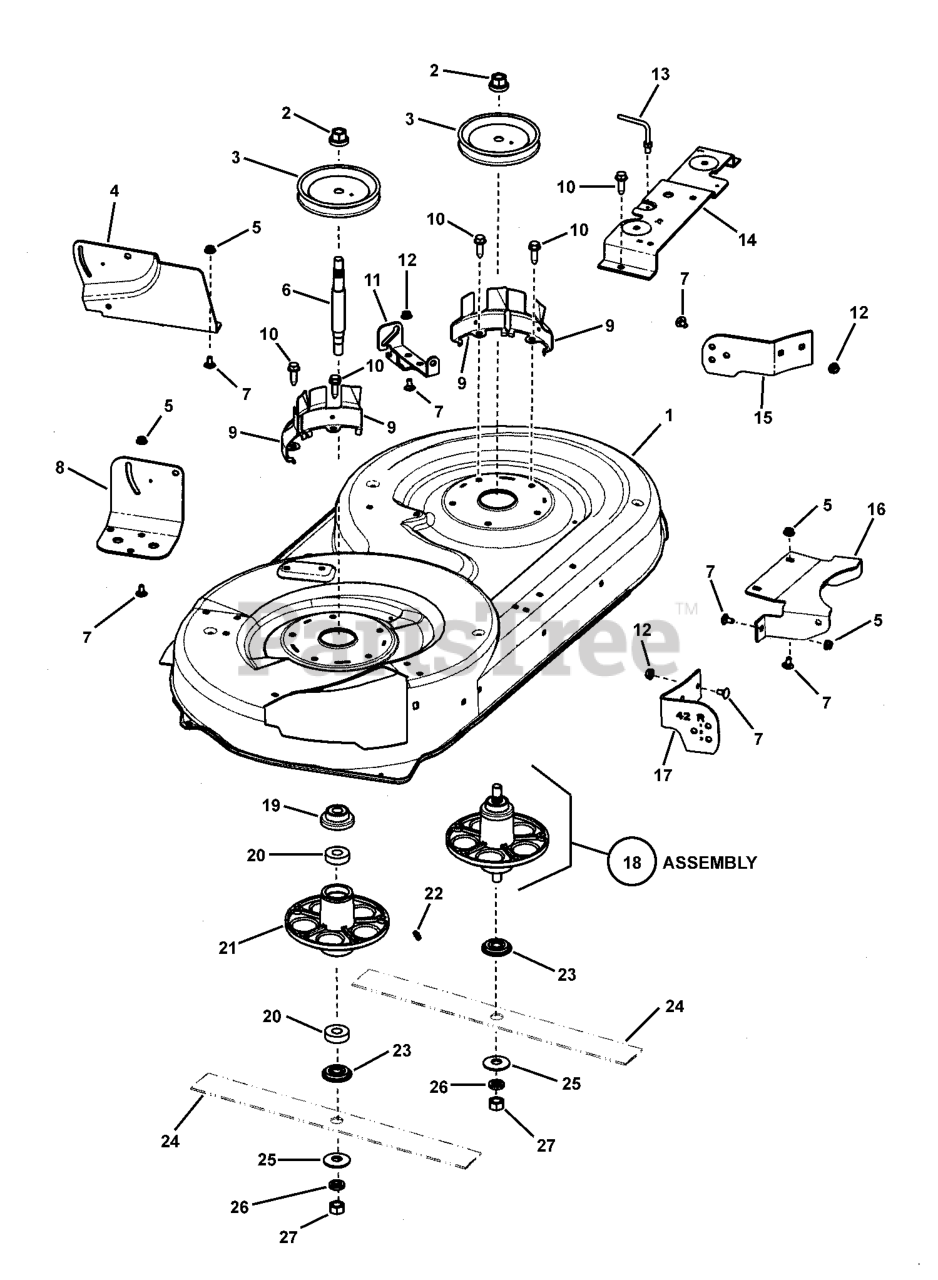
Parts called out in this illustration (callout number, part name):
1	HOUSING, 42" Mower Deck
2	NUT-NYLOCK RING - PULLEY 9/16-18
3	PULLEY, JACKSHAFT
4	BRACKET SUSPENSION, L.H. 42
5	HEX NUT, 5/16-18 FLANGE SER YZ
6	SHAFT, SPLINED
7	BOLT CARRIAGE, 5/16-18 X .62
8	BRACKET SUSPENSION, R.H. 42
9	SEGMENT - BELT GUIDE
10	HHST, 3/8-16X1.25
11	BRACKET - HINGE
12	NUT, HEX FLANGE LOCK, 5/16-18 NC
13	BELT GUIDE (5/16-18)
14	BRACKET - BRAKE MTG 42"
15	BRACKET LR GA WHEEL
16	BRACKET, FRONT HANGER
17	BRKT RH GAGE WHEEL 42"
18	JACKSHAFT HOUSING ASSY
19	SPACER, PULLEY
20	BALL BEARING, JACKSHAFT
21	JACKSHAFT HOUSING
22	FITTING - LUBRICATION
23	BLADE ADAPTER
24	BLADE, 42 (3N1)
25	HER-BELLEVILLE 1.0 X .625 X .200
26	HER - HARDENED 1.0OD X .625ID X .188
27	NUT, BLADE, 9/16-18 ZINC PLATE YELLOW CHROMATE
